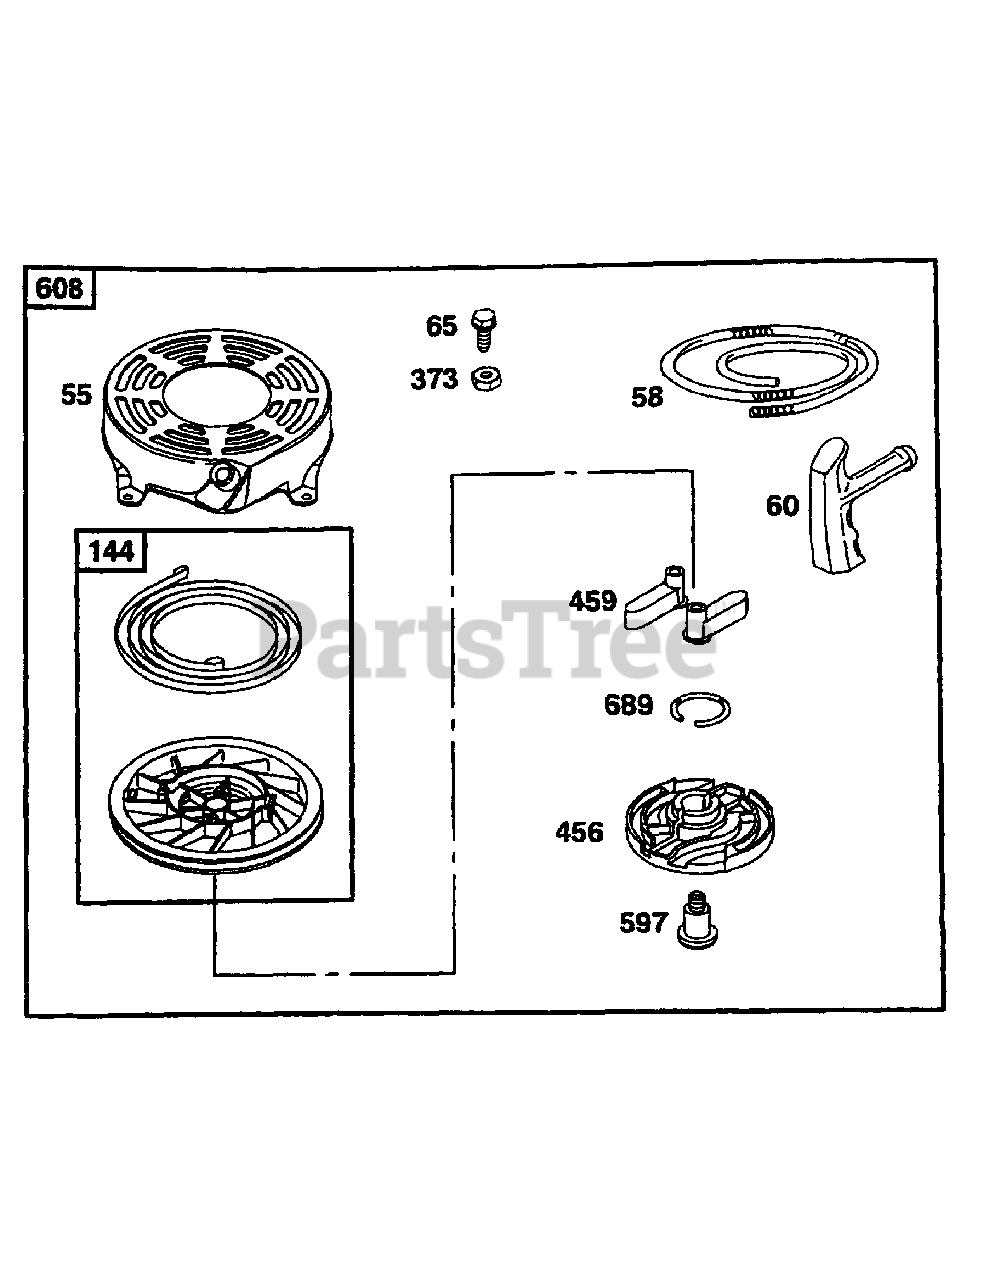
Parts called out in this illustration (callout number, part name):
55	Rewind Starter Housing
58	Starter Rope
60	Starter Rope Grip
65	Hex Screw
144	Starter Pulley
373	Hex Nut
456	Spring Retainer
597	Shoulder Screw
608	Rewind Stater Assembly
689	Friction Spring
